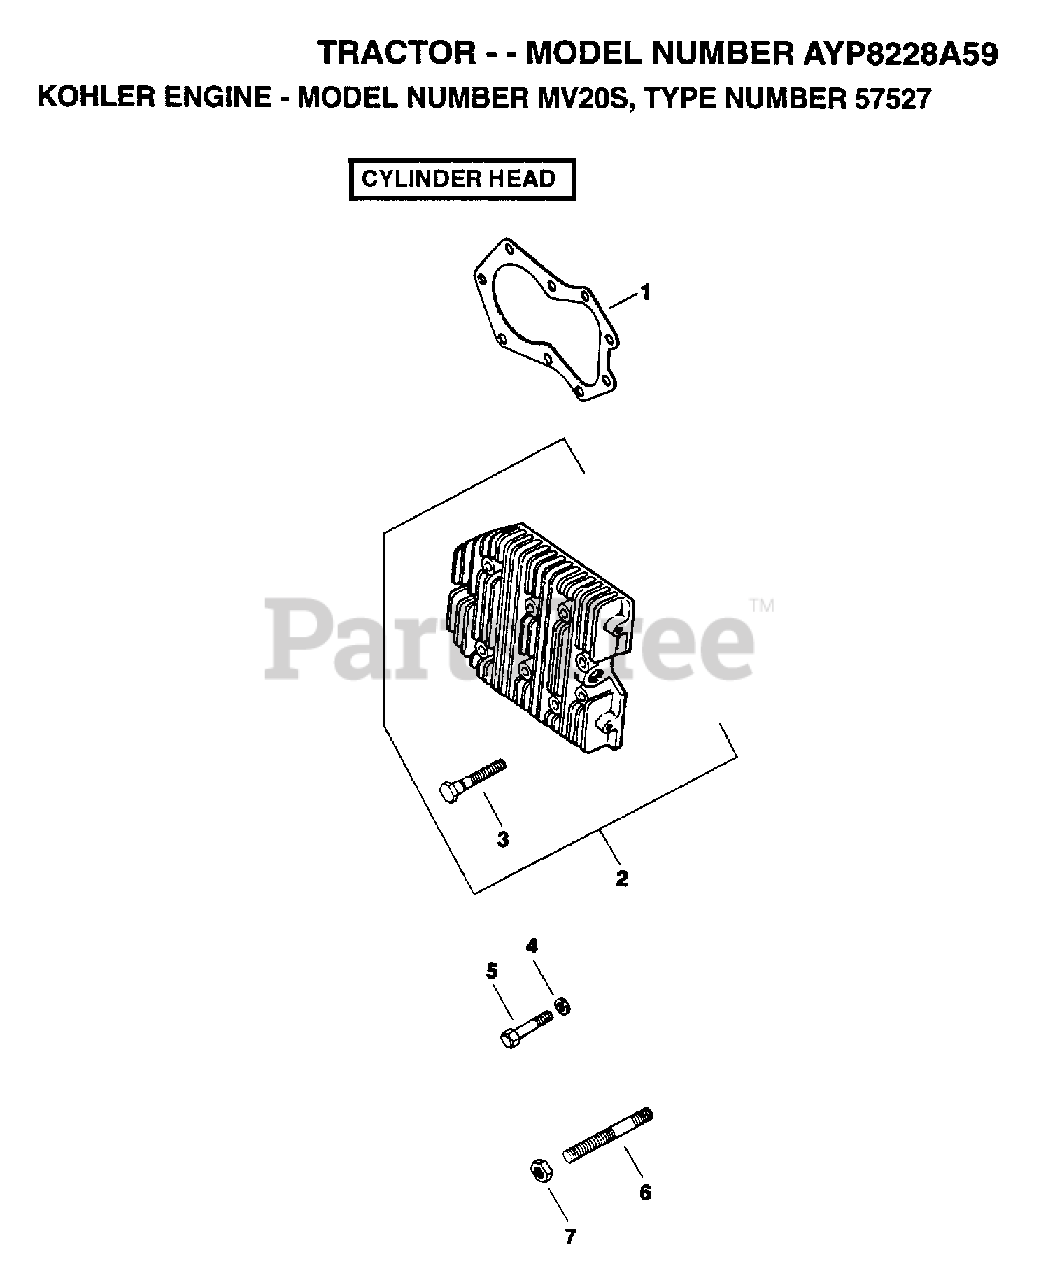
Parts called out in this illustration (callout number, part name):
2	KIT, CYL. HEAD
4	WASHER
7	NUT
